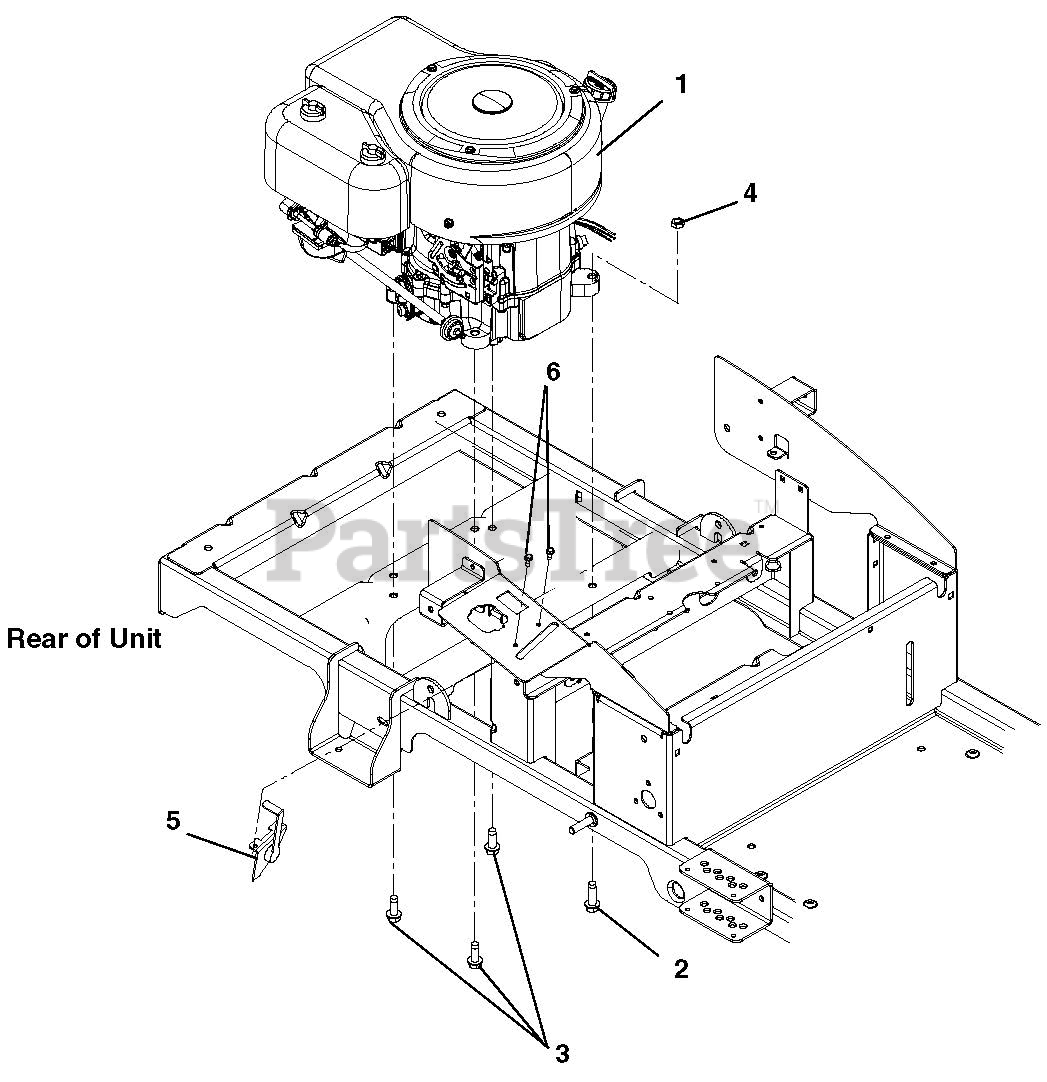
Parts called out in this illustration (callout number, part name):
1	ENGINE, 13.5HP BRIGGS IC
2	@SCR-TAP .38-16X1.25 HWH TR YZ
3	@SCR-TAP .38-16X1.00 HWH TR YZ
4	@NUT-LK-CTR-JAM .375-16 YWZC
5	THROTTLE/CHOKE CABLE
6	@SCR-TAP 10-24X.50 HWH TR YWZC
